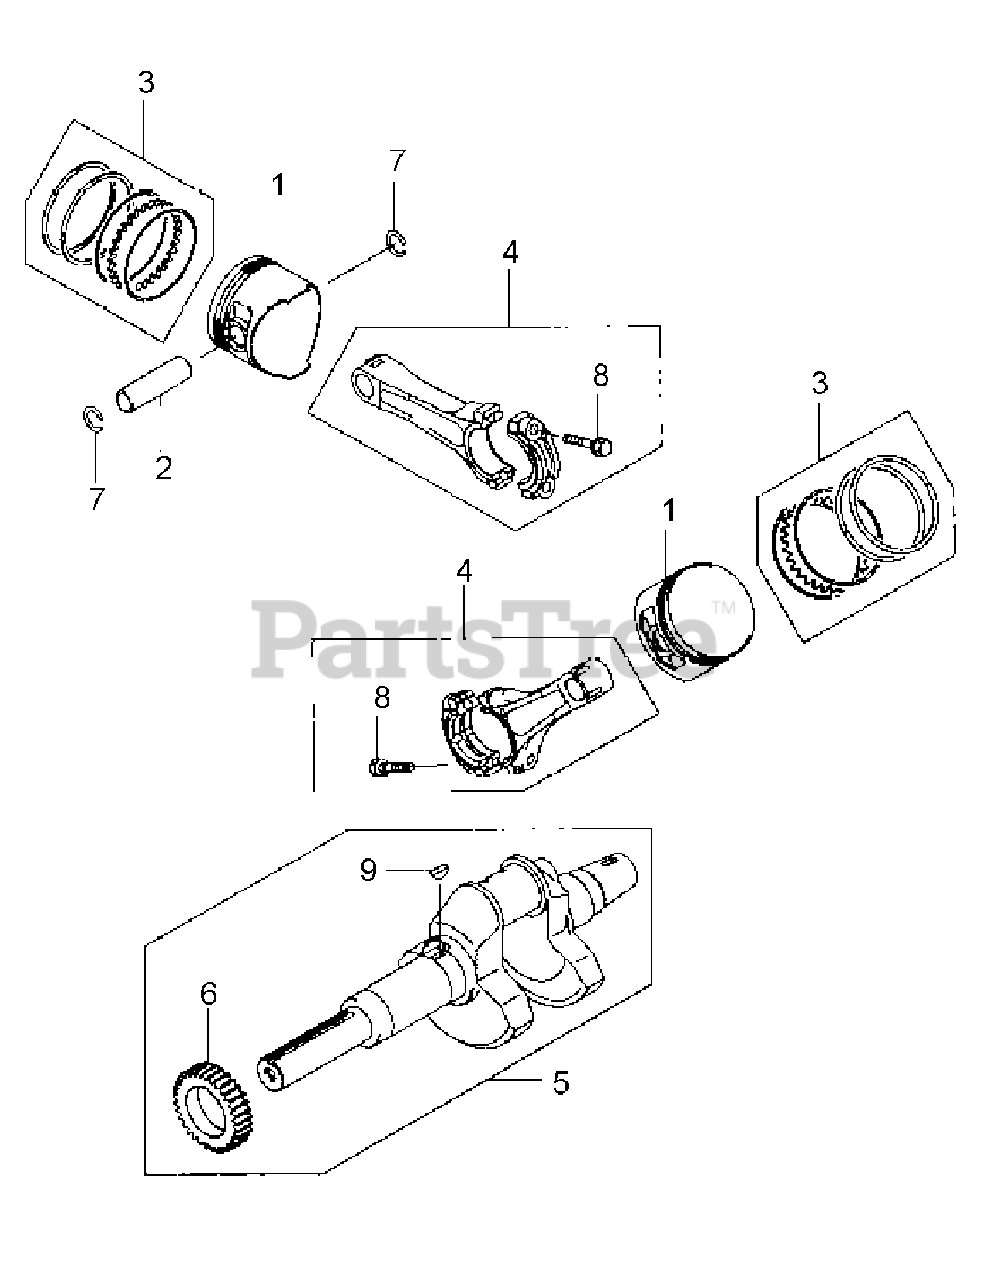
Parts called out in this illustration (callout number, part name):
1	ENGINE PISTON
1	ENGINE PISTON (.50)
3	PISTON RING SET
3	PISTON RING SET (.50)
4	CONNECTING ROD ASSY.
5	CRANKSHAFT ASSY.
6	SPUR GEAR 33T
9	WOODRUFF KEY
